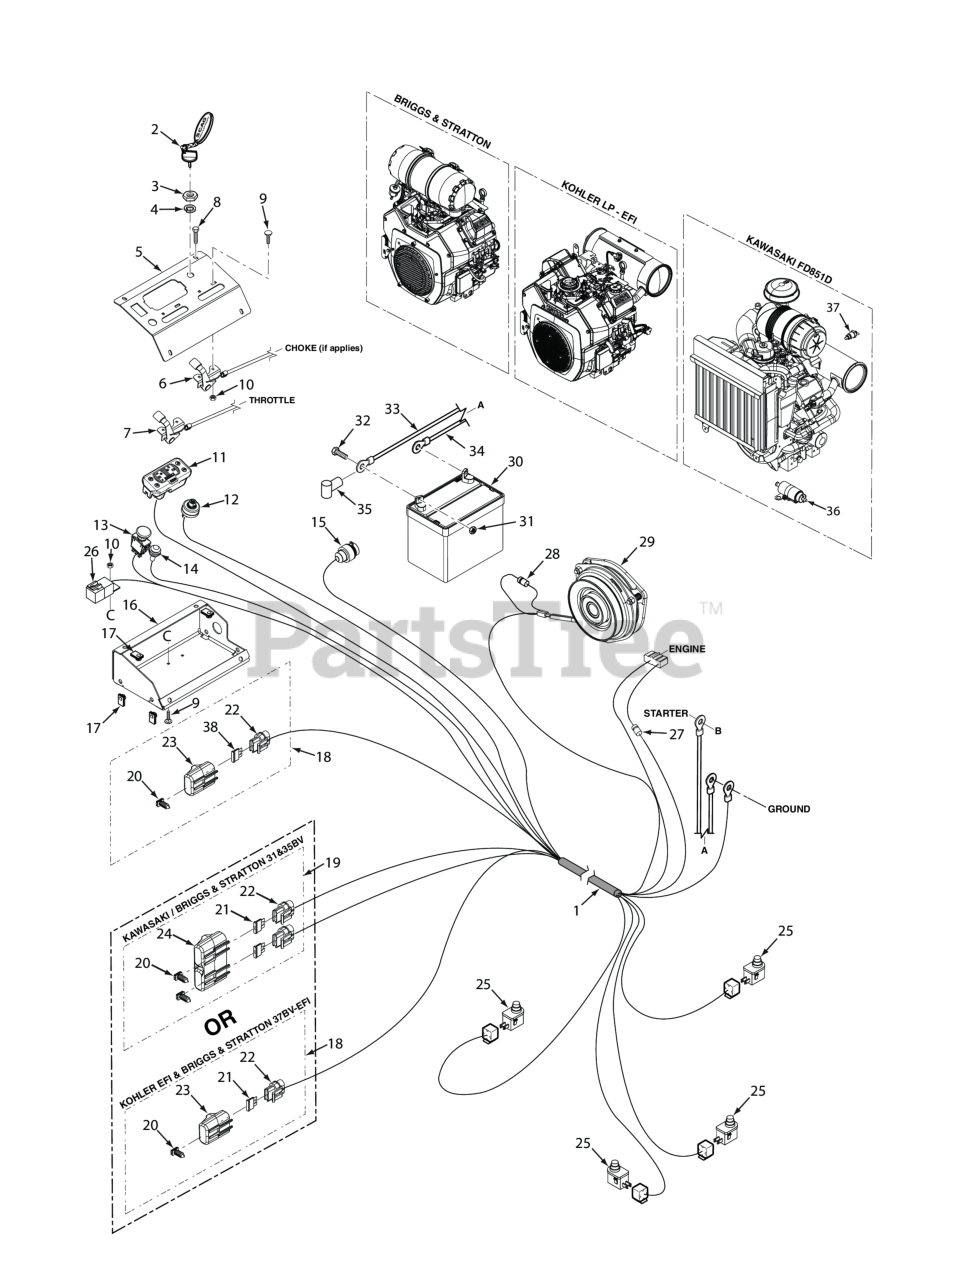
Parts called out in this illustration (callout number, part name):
1	Wire Harness, STTII-EFI (Kohler EFI-LP)
2	Key, Assembly w/Fob
3	Nut, 5/8-32 Special
4	LOCK WASHER, 5/8" INTERNAL TOOTH
5	Instrument Panel w/Decal
7	Control Cable (Briggs & Stratton)
8	Bolt, Hex Head Serrated Flange 1/4-20 x 3/4"
9	Bolt, Carriage #10-24 x 1/2"
10	Nut, Elastic Stop #10-24
11	Tiger Eye, Cluster Gauge
12	KEY SWITCH(INCLUDES MOUNTING HARDWARE)
13	Switch, PTO - 10 Amp
14	Indicator Light, Glow Plugs (Includes Mounting Hardware)
15	Power Plug, 12V
16	Base, Instrument Panel
17	Bolt, Hex Head 3/8-16 x 1"
18	Single Fuse Assy., Excluding Fuse
19	Double Fuse Assy.
20	Clip, Fuse Holder
21	FUSE, 20 AMP BLADE TYPE AUTOMOTIVE
22	Fuse Holder Assembly
23	Cover, Sealed Single
24	Cover, Sealed Double
25	Switch, Interlock, Normally Open
26	Relay, 12V 40 AMP Standard
27	Decal, Forward Speed Selector
28	Diode, 600V 6 Amp
29	Electric Clutch w/Tag - GT-3.5 (FX850)
30	Battery, 350 CCA
31	Nut, 1/4 - 20 Hex
32	Bolt, Hex Head 1/4-20 x .5" Battery, (Not Available Through Scag)
33	Battery Cable, 44" Red w/Braid (26EFI) - Kohler
34	Battery Cable, 39" Black (26EFI) - Kohler
35	RUBBER BOOT
36	Fuel Pump
37	Sender Unit, Water Temp. (Liquid Cooled Only)
38	Fuse, 5 Amp
